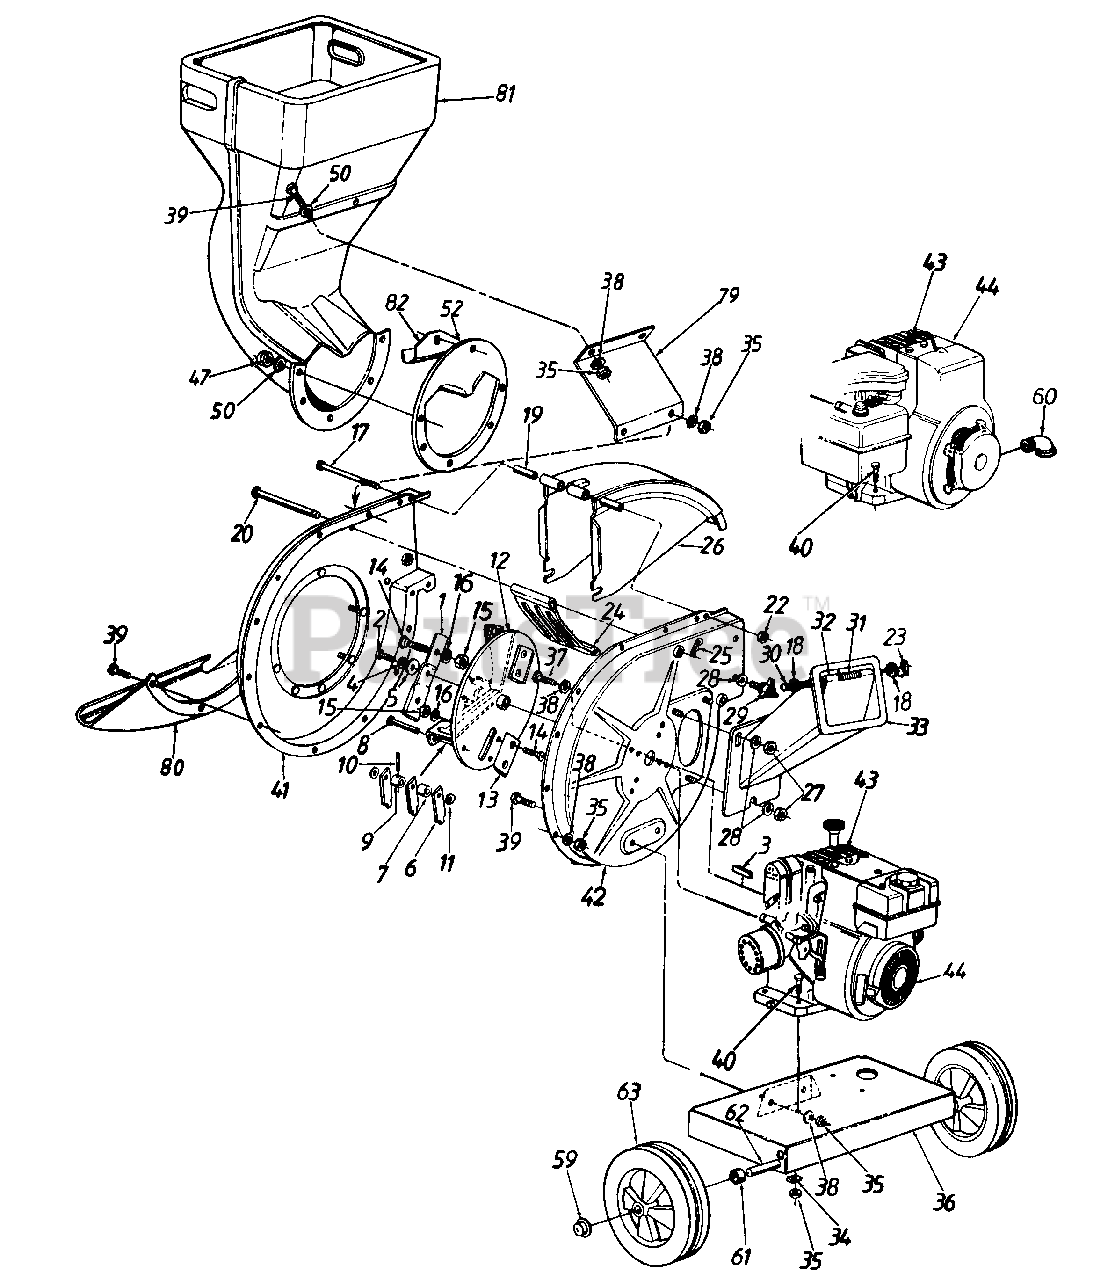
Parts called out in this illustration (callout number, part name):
1	Blade
2	Hex Patch Bolt 3/8-24 x 2" Lg. (Gr. 8)
3	Sq. Key 1/4 x 2.0" Lg.
4	L-Wash. 3/8" I.D. H.D.
5	Fl-Wash .406" I.D. x 1.25" O.D. Hdn.
6	Flail
7	Flail Spacer
8	Clevis Pin .496" Dia.
9	Flail Spacer w/.160" Dia. Hole
10	Spring Roll Pin 1.125" Lg.
11	Fl-Wash .531" I.D. x .94" O.D.
12	Impeller Ass'y. Comp.
13	Chipper Blade
14	Flat Hd. Scr. 5/16-24 x .75" Lg.
15	Hex Top L-Nut 5/16-24 (Gr. 5)
16	L-Wash. 5/16" I.D.
17	Hex Bolt 1/4-20 x 3.75" Lg.
18	Fl-Wash .281" I.D. x .50" O.D.
19	Chute Hinge Spacer 1.66" Lg.
20	Clevis Pin .5" Dia. x 4.62" Lg.
22	Hex Ctr. L-Nut 1/4-20 Thd.
23	Cotter Pin
25	Internal Cotter Pin 3/8" Dia.
27	Hex Nut 5/16-18 Thd. (Gr. 5)
28	Bell-Wash .345" I.D. x .88"
29	Hand Knob
30	Chipper Door Rod
31	Torsion Spring 1.14" Lg.
35	Hex Nut 5/16-18 Thd. (Gr. 5)
37	Hex Bolt 5/16-24 x .75" Lg.
38	L-Wash. 5/16" I.D.
39	Hex Bolt 5/16-18 x .75" Lg. (Gr. 5)
40	Hex Bolt 5/16-18 x 1.5" Lg.
44	Engine
47	Elastic Lock Nut 5/16-18 Thd.
50	Fl-Wash. 5/16" I.D.
52	Back-Up Plate
59	Push Cap 5/8" Dia. Rod
60	Drain Elbow (5 HP B&S)
61	Spacer.64" I.D. x .38" Lg.
62	Shredder Axle
63	Wheel Ass'y. Comp.
81	Leaf Hopper
